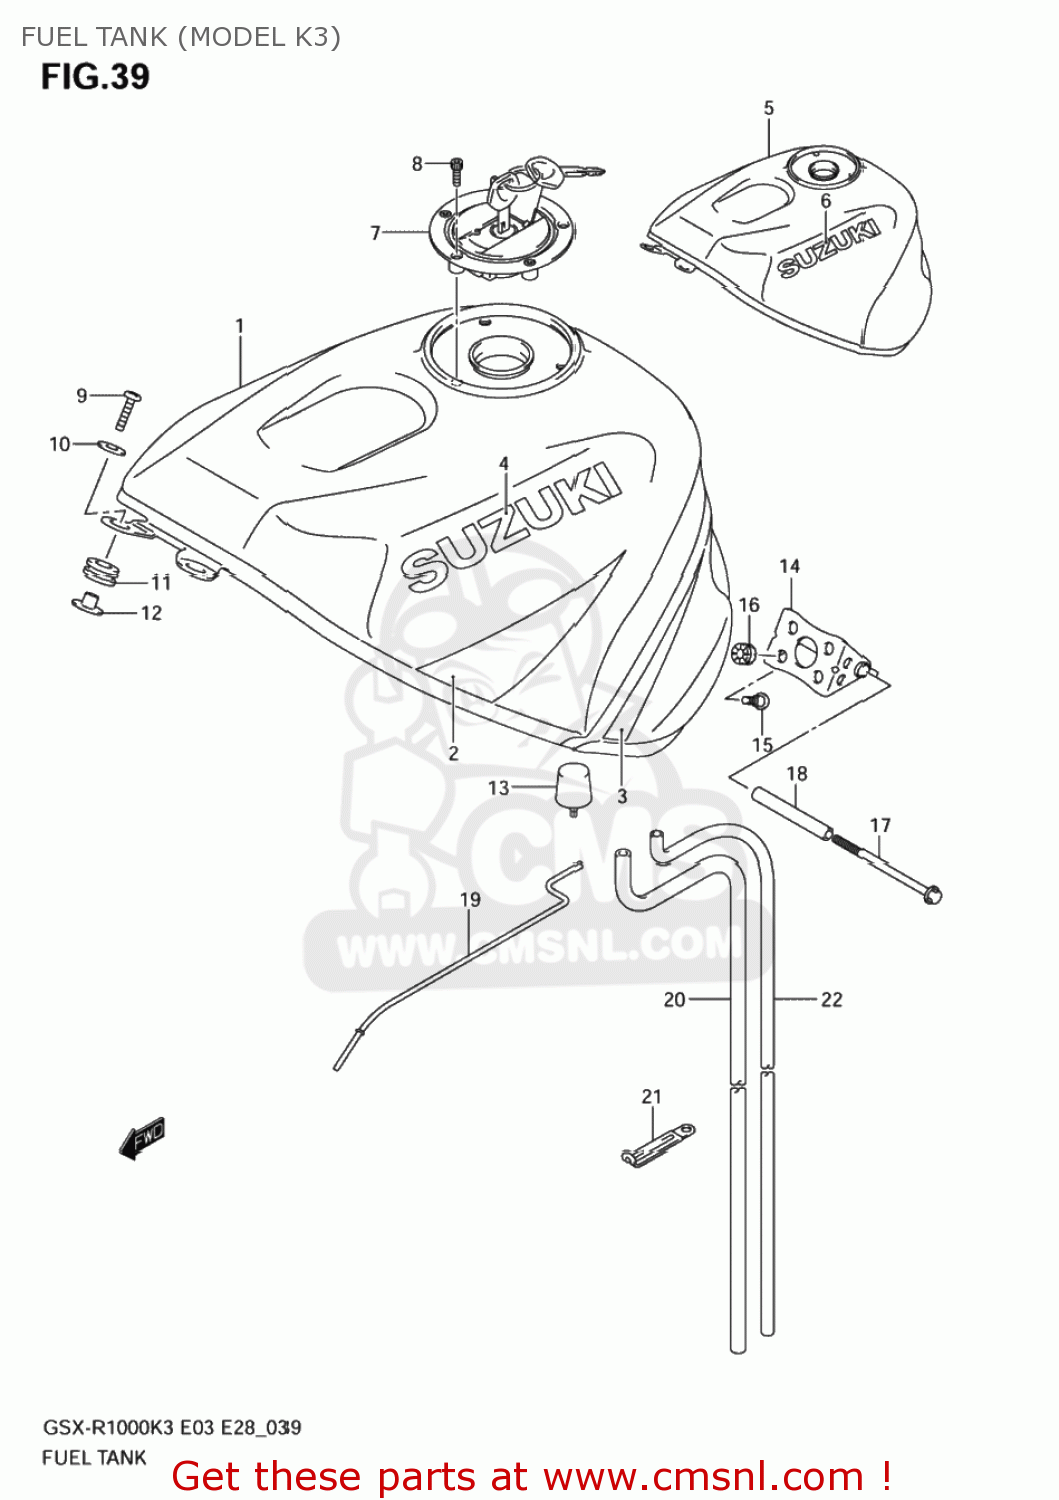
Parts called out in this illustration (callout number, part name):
1	TANK ASSY,FUEL
2	TAPE SET,FUEL TANK UPR
3	TAPE SET,FUEL TANK LWR
4	EMBLEM,FUEL TANK
5	TANK ASSY,FUEL(SILVER)
6	EMBLEM
7	CAP SET,FUEL TANK
8	BOLT(5X20)
9	SCREW(6X25)
10	WASHER(6.5X22X1.6)
11	CUSHION,FUEL TANK FR
12	SPACER,FUEL TANK FR
13	CUSHION,FUEL TANK RR
14	BRACKET,FUEL TANK NO.1
15	SCREW,FUEL TAN
16	CUSHION
17	BOLT(6X110)
18	SPACER,FUEL TANK RR
19	STAY,FUEL TANK
20	HOSE,WATER DRAIN
21	CLAMP(L:65)
22	HOSE,FUEL TANK BREATHER
